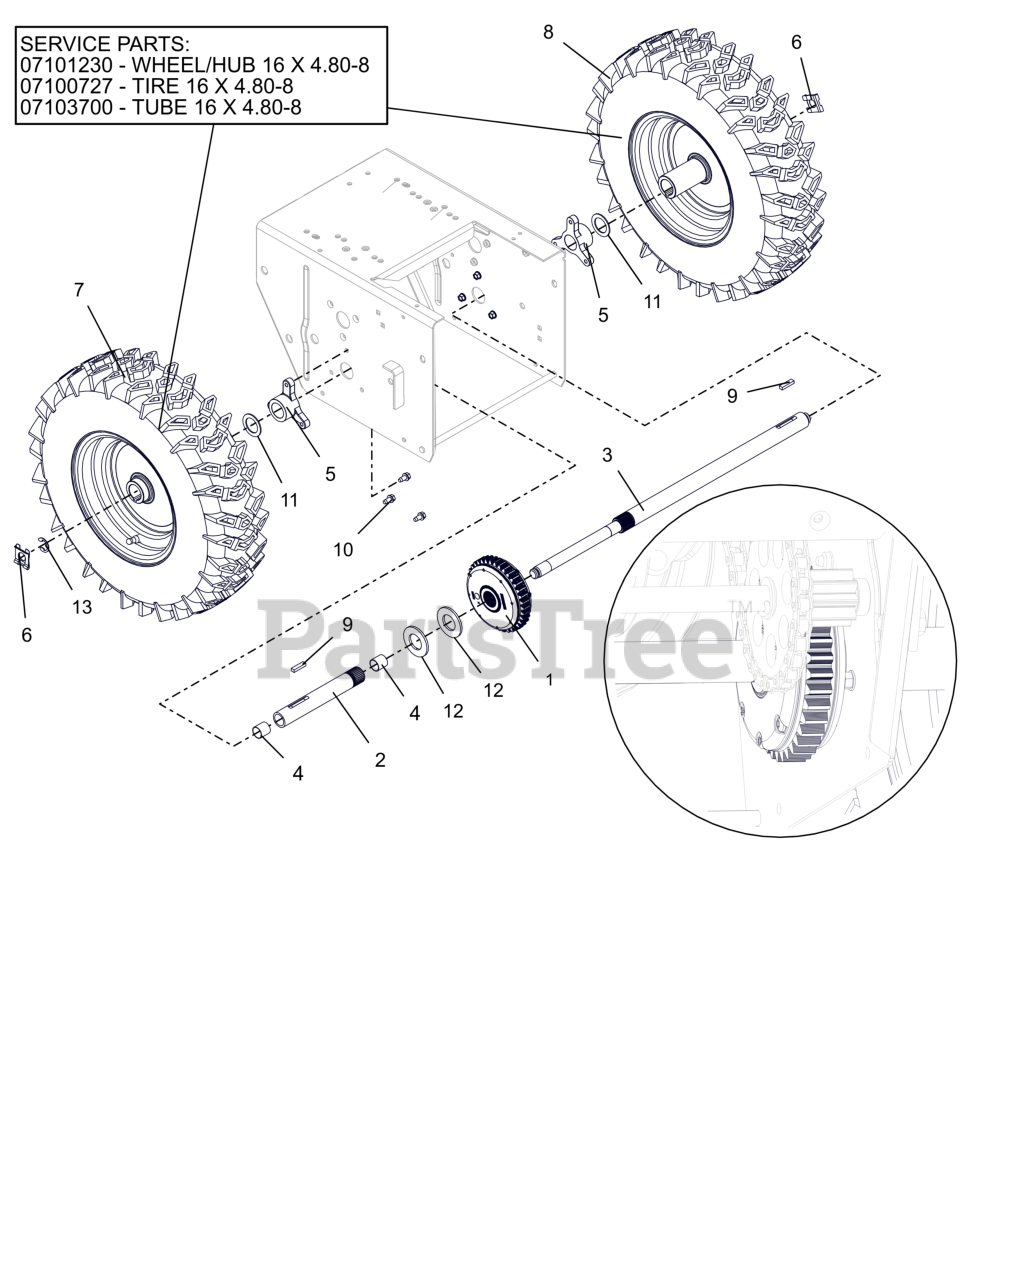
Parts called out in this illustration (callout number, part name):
1	DIFFERENTIAL, AUTOMATIC
2	AXLE, SHORT - W/BUSHINGS
3	AXLE,LONG-DELUXE AUTO DIFF
4	BSHG-SLV .706X.764X.75 BRZ
5	BUSHING, AXLE
6	CLIP, SNAP .625 DIA
7	TIRE/WHEEL,RH 16X4.8-8 DIFF T2
8	TIRE/WHEEL,LH 16X4.8-8 DIFF T2
8	HUB, WHEEL-16X4.8-8
8	TIRE, 4.80-8 K478
8	TUBE
9	KEY-RECT .25X.188X1.00
10	SCR-TAP .25-20X.50 HWH ZCC
11	WSHR, FLT 1.010X1.505X.062 ZCC
12	WSHR, FLT 1.062X2.000X.134 ZCC
13	RG-RTNG-EXT .625X.042
